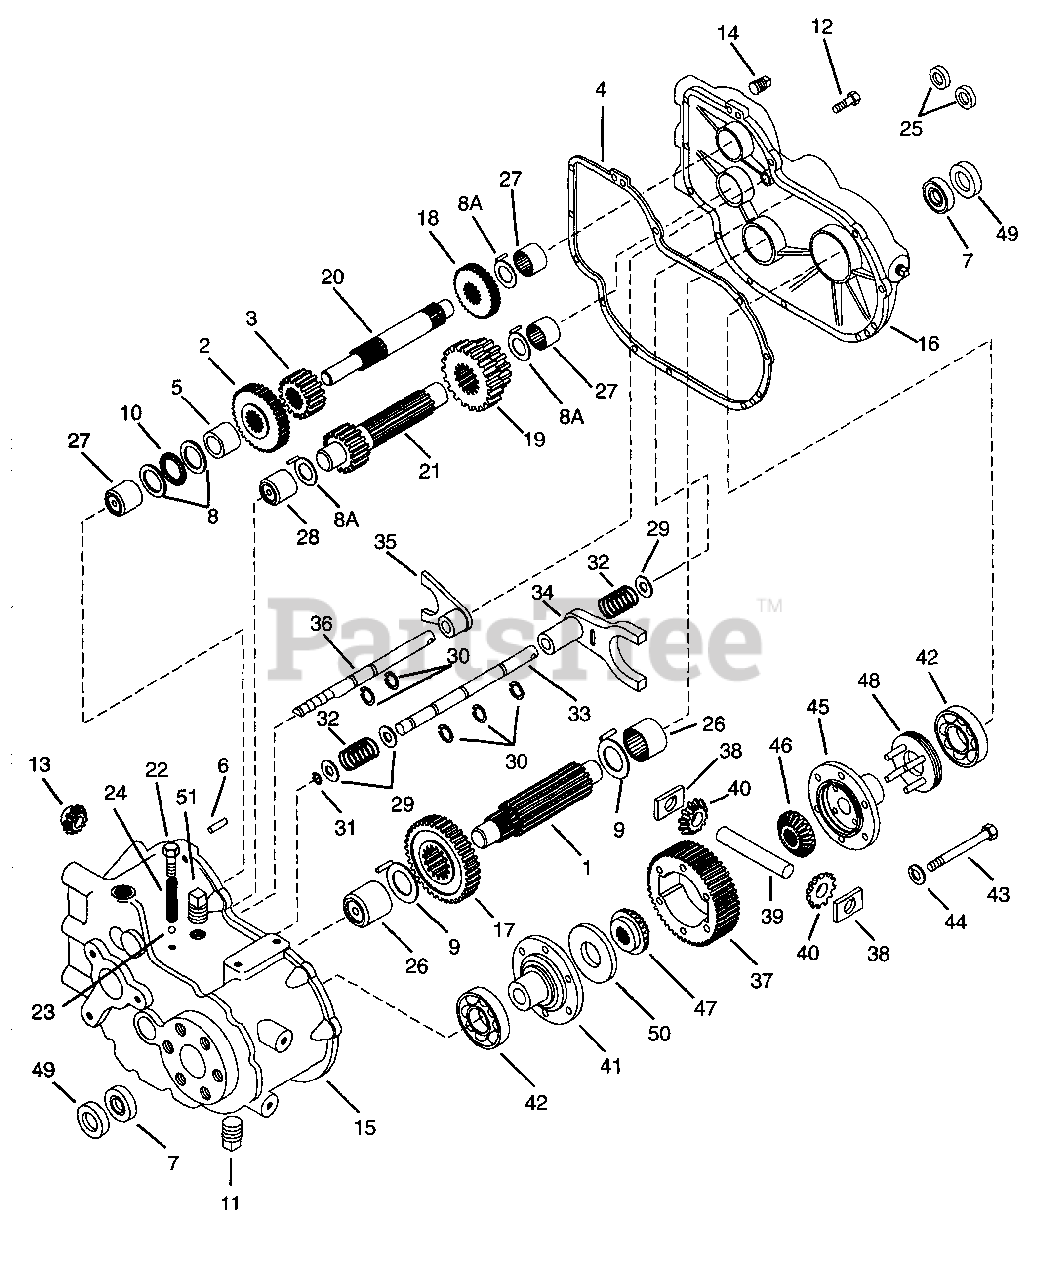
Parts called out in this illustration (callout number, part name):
1	Pinion, Output
2	Gear, Bevel
3	Gear, Spur
4	Gasket, Case & Cover
5	Spacer,
6	Pin. Dowel
7	Seal, Oil
8	Washer, Thrust
8A	Wshr, Thrust
9	Wshr, Thrust
10	Bearing, Thrust
11	Plub, Magnetic Drain, 3/8-18
12	Screw, Hex Hd. Threadforming, 5/16-18 x 1
13	Pinion, Bevel
14	Plub, Pipe, 1/8-27
15	Case Assy., Transaxle
16	Cover, Assy., Transaxle
17	Gear, Output
18	Gear, Spur
19	Gear, Cluster
20	Shaft, Counter
21	Shaft & Gear Shifter
22	Screw, hex Flanged Hd., 1/4-20 x 5/8
23	Ball, Steel, 3/16"
24	Spring, Shifter Fork
25	Seal, Oil
26	Bearing, Needle
27	Bearing, Needle
28	Bearing, Needle
29	Washer, Thrust
30	Ring, Retaining
31	Ring, Retaining
32	Spring, Compression
33	Rod, Shift
34	Fork, Shift
35	Fork, Shift
36	Rod, Shift
37	Gear, Ring
38	Block, Drive
39	Pin, Drive
40	Pinion, Bevel
41	Carrier, Differential
42	Bearing, Ball
43	Screw, Hex Flanged Hd., 3/8-16 x 2-3/4
44	Lockwasher, 3/8"
45	Carrier, Differential
46	Gear, Bevel
47	Gear, Bevel
48	Collar Assembly, Shift
49	Spacer
50	Washer, Thrust
51	Plug, 3/8-18 Sq. Hd. Pipe
